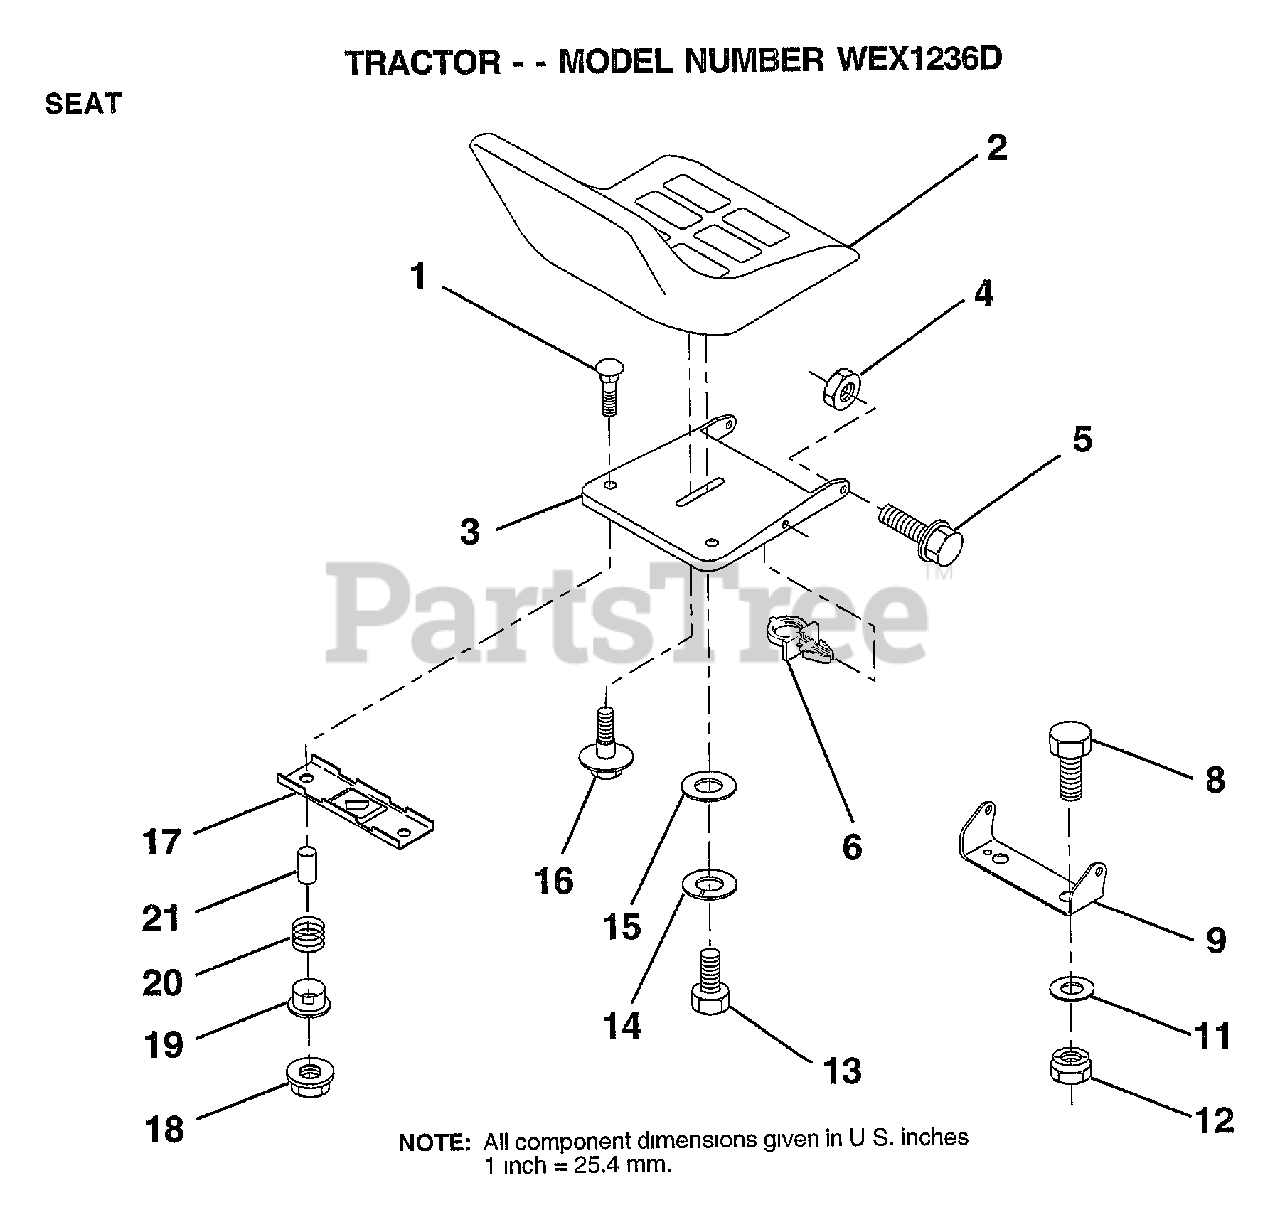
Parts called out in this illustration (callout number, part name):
1	BOLT-RD HD SQ NK
3	PAN-SEAT
4	NUT
5	BOLT
6	CLIP.PUSH-IN.HING
8	BOLT
9	BRACKET PVT SEAT
11	WASHER
12	NUT
13	BOLT
14	LOCKWASHER
15	WASHER
16	"BOLT,SHOULDER"
17	BRKT SWITCH
19	BUSHING
20	SPRING
21	SPLIT SPACER
